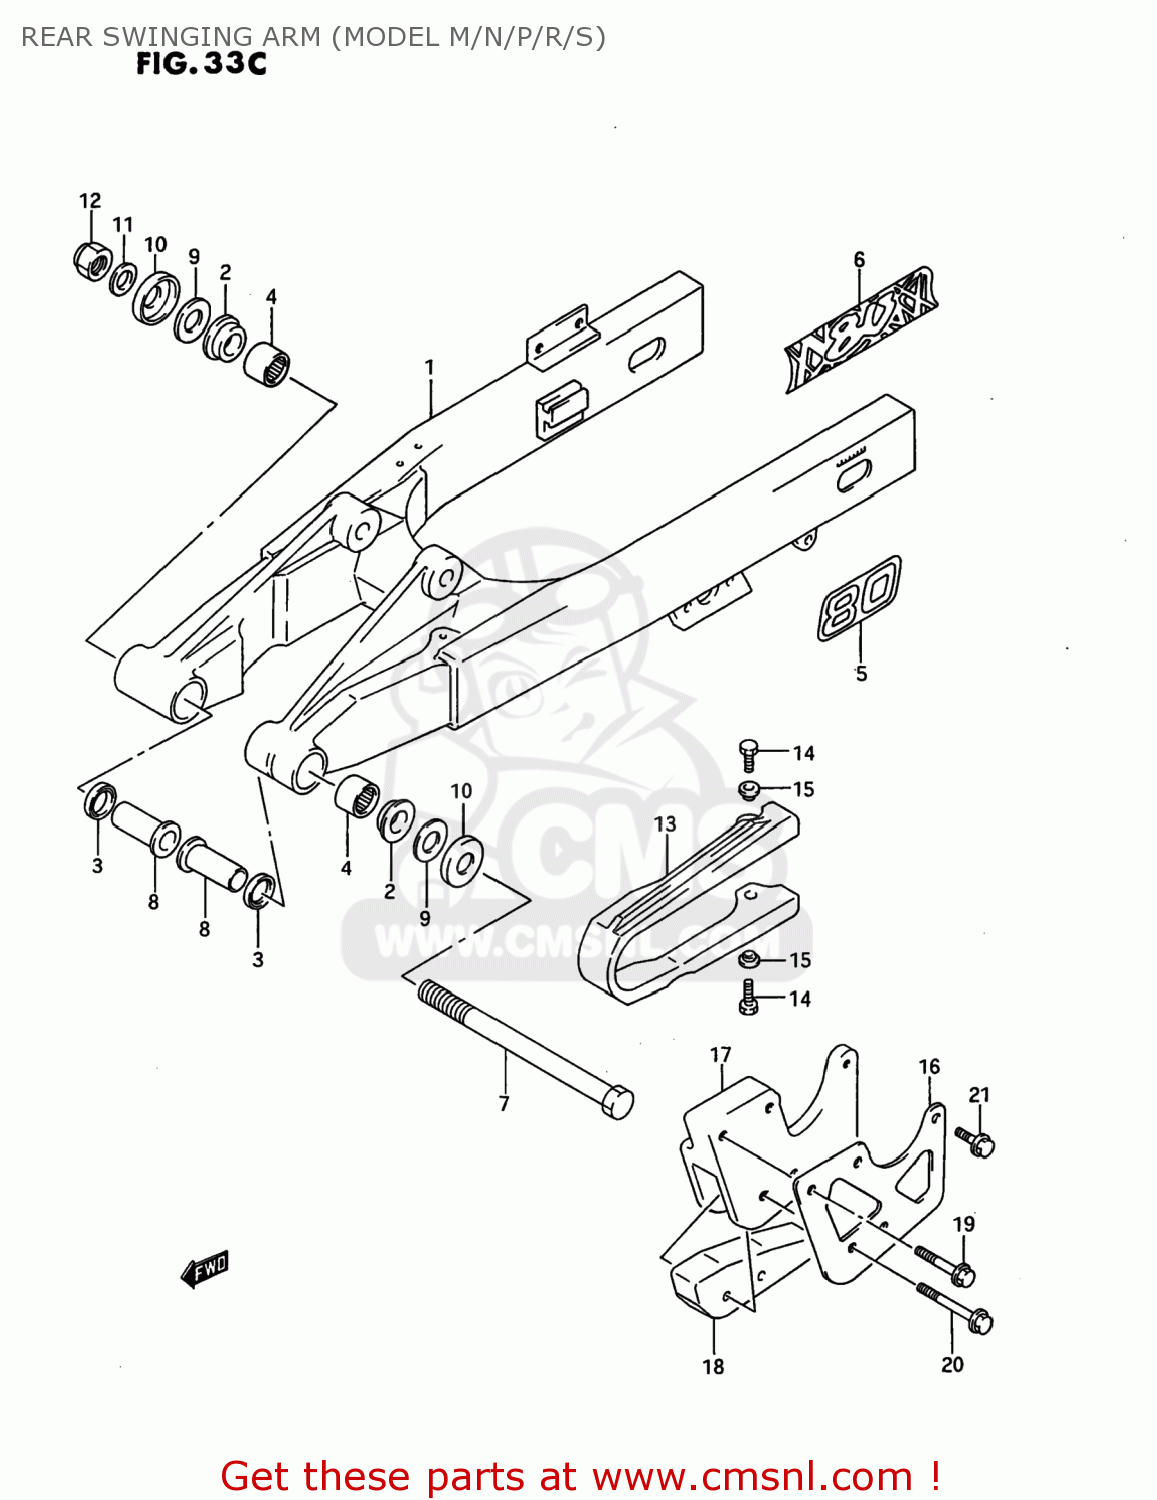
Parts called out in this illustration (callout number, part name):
1	SWINGINGARM ASSY,RR
2	BUSHING,SWGARM PIVOT
3	SEAL,OIL(17X24X3)
4	BEARING(17X24X30)
5	EMBLEM,SWING ARM
6	EMBLEM,SWING ARM
7	SHAFT,RR SWINGINGARM PIVOT
8	SPACER,RR SWGARM PIVOT
9	WASHER
10	COVER,SWGARM PIVOT
11	WASHER
12	NUT 12MM
13	BUFFER,CHAIN TOUCH DEFENSE
14	BOLT
15	WASHER
16	PLATE,GUIDE CHAIN OUTER
17	GUIDE,CHAIN
18	DEFENSE,CHAIN GUIDE
19	BOLT
20	BOLT
21	BOLT
